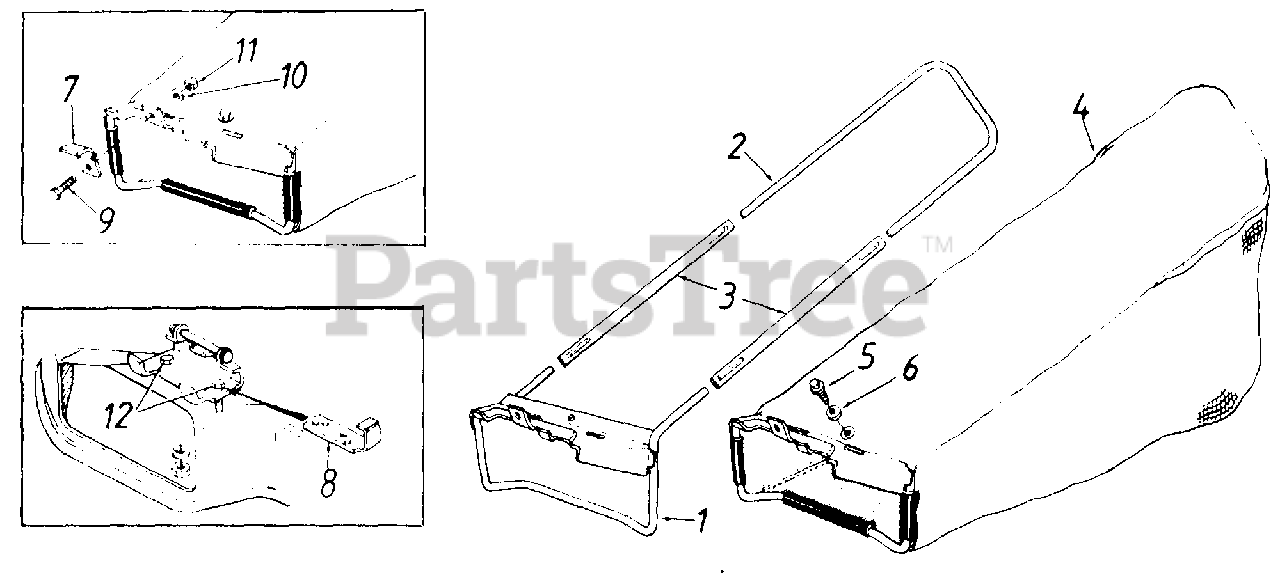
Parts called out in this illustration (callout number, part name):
1	Frame - Lower Ass'y.
4	Grass Bag
5	Hex Wash Hd. TT-Tap Scr. 1/4-20 x 5" Lg.
6	Bell-Wash. 1/4" I.D.
7	Deflector Stop
8	Support Plate
9	Hex Bolt 1/4 20 x .5" Lg.
10	L-Wash. 1/4" I.D.
11	Hex Nut 1/4-20 Thd.
12	Hex Bolt 1/4 20 x .62" Lg.
